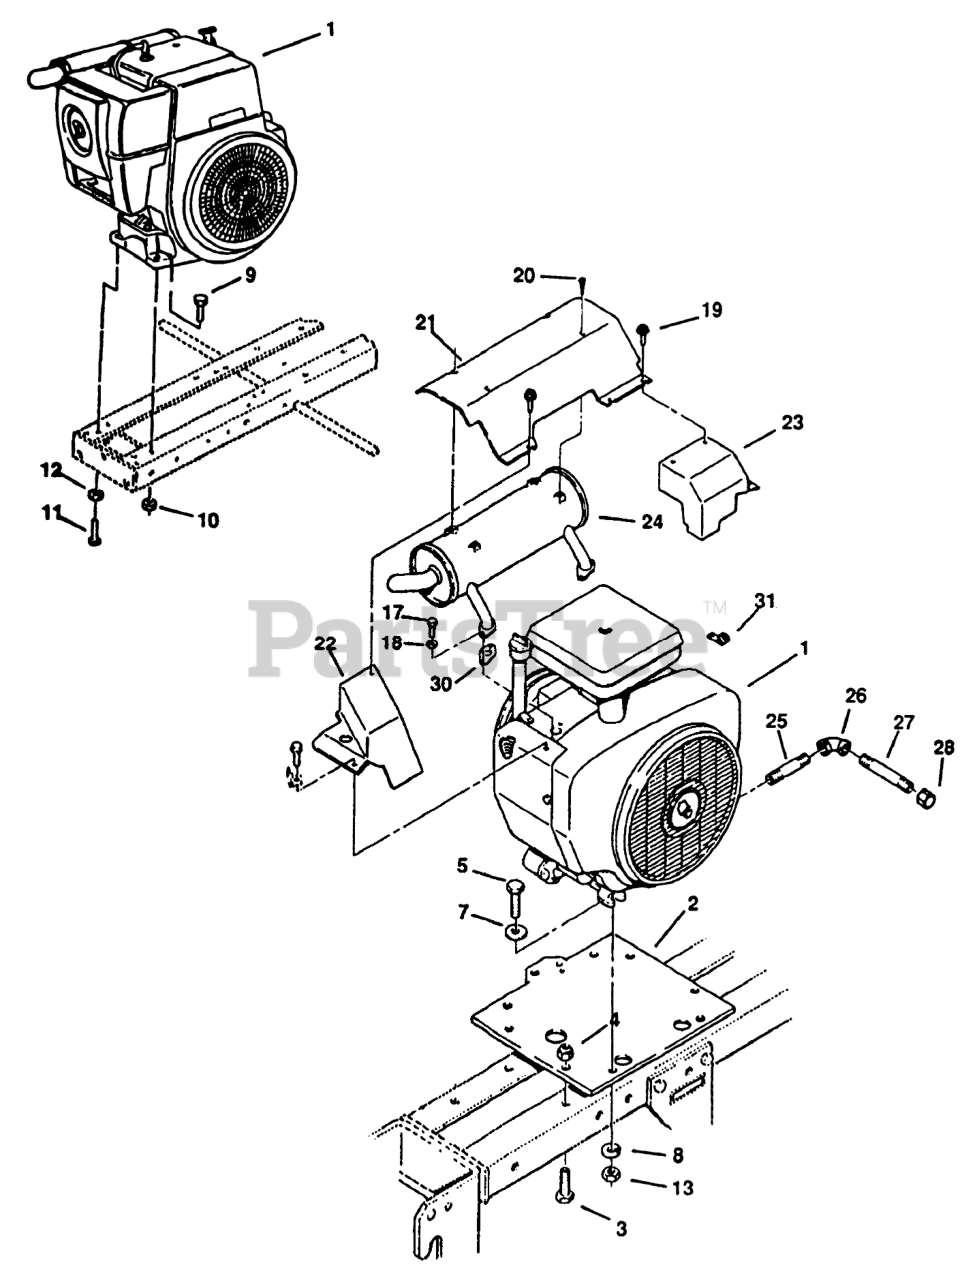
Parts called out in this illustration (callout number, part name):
2	PLATE-ENGINE B
3	Bolt
5	Bolt
7	WASHER-FLAT
8	WASHER-LOCK/SP
9	SCREW-HH
10	NUT-LOCK, NI
11	SCREW-HH
12	WASHER-LOCK
13	NUT-HEX
17	SCREW-HH
18	WASHER-LOCK
19	SCREW-HH
20	Screw
21	Air Deflector
22	LH Exhaust Cover
23	RH Exhaust Cover
24	MUFFLER-EXHAUST
25	Pipe
26	ELBOW 3/8 90 DEG
27	PIPE-NIPPLE 3/8 X 4"
28	Cap
30	Exhaust Gasket
31	J-CLIP
